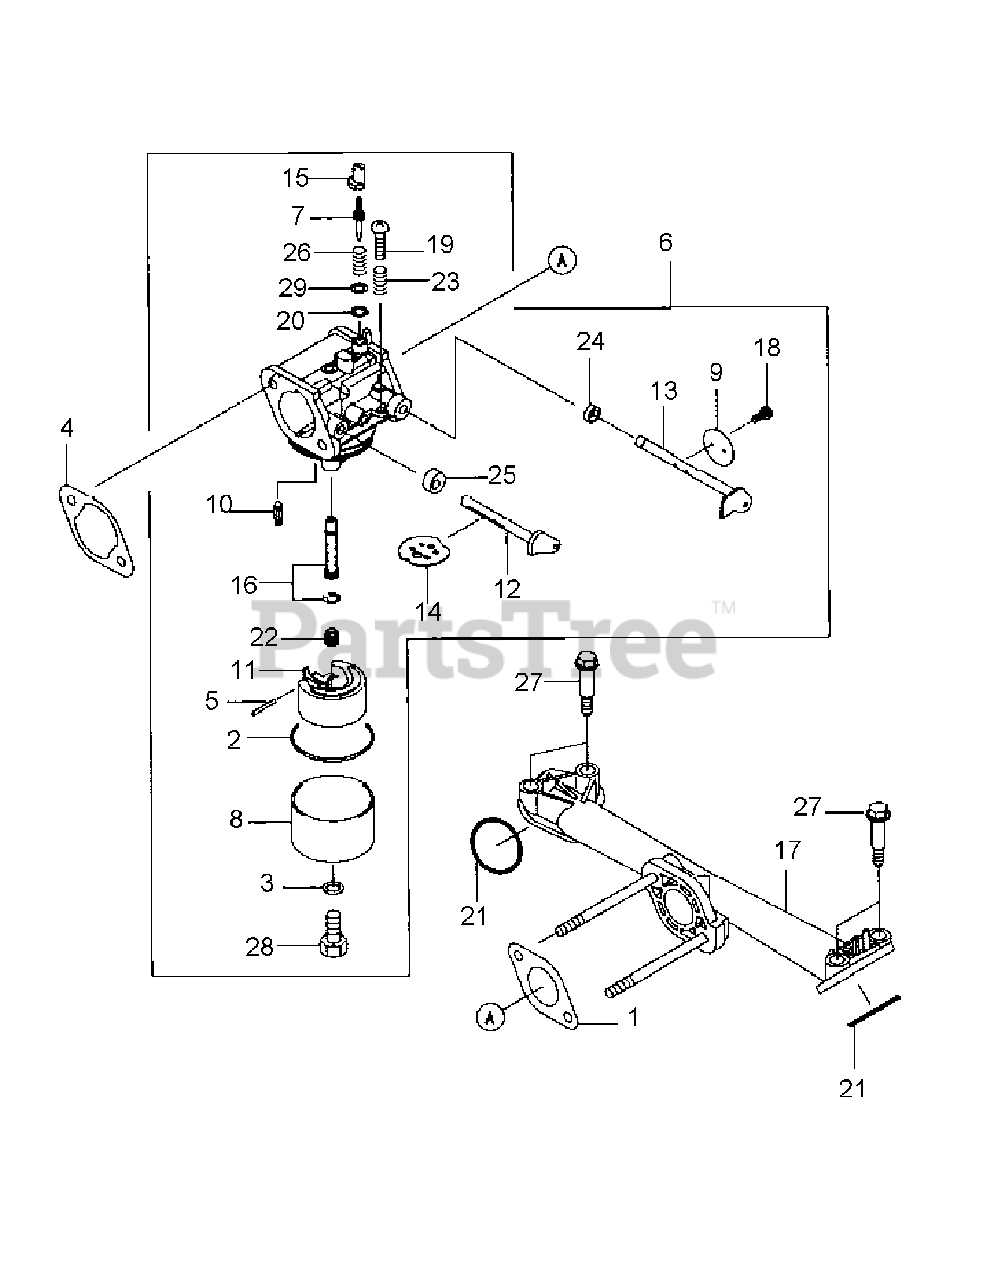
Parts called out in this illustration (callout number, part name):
1	INSULATOR GASKET
2	CHAMBER GASKET
4	AIR CLEANER GASKET
6	CARBURETOR ASSY.
7	PILOT AIR SCREW
9	THROTTLE VALVE
13	THROTTLE SHAFT
14	CHOKE VALVE ASSY.
17	INTAKE MANIFOLD
20	O-RING
